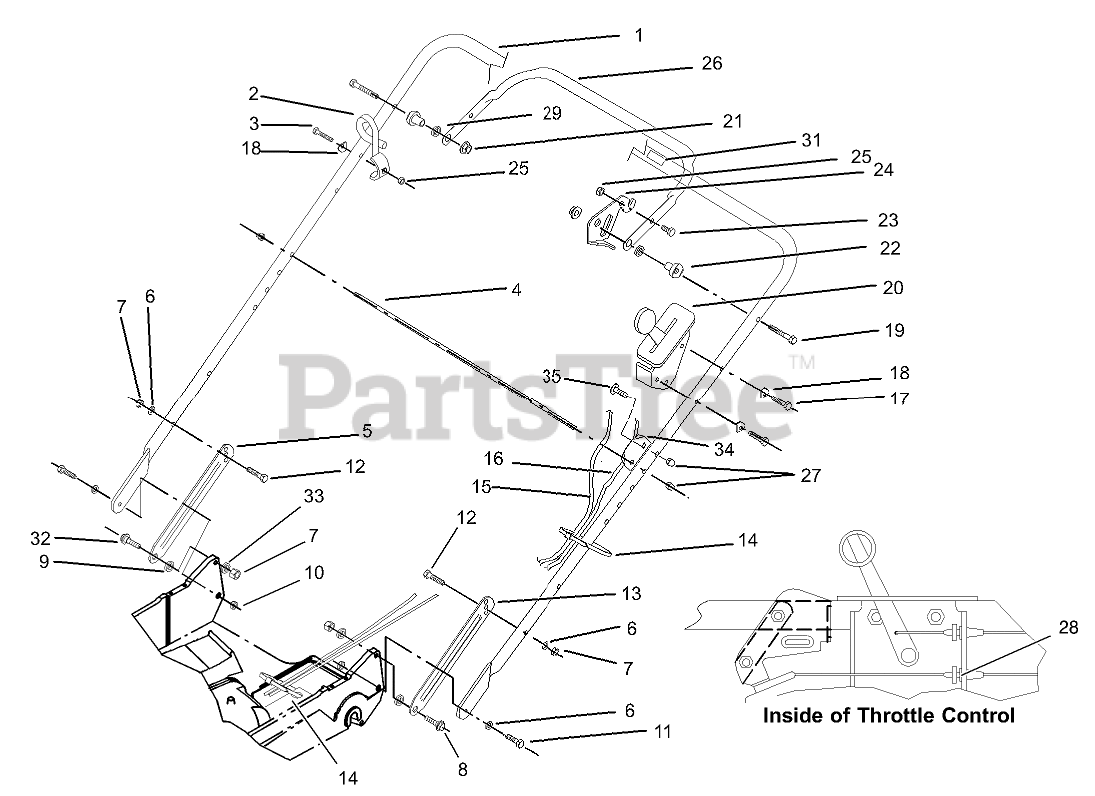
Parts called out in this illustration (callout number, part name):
2	GUIDE-ROPE
3	SCREW-HH
4	ROD-SUPPORT, BAG
5	LATCH-HANDLE, RH
6	WASHER-BELLEVILLE
7	NUT-LOCK, NI
8	SCREW-SHOULDER
9	SPACER
10	NUT-LOCK, NI
11	SCREW-HH
12	SCREW-HH
13	LATCH-HANDLE, LH
14	TIE-CABLE
15	Cable-Brake
16	CABLE-THROTTLE
17	SCREW-HH
18	WASHER
19	SCREW-HH
20	Control-Throttle
21	NUT-LOCK, NI
22	SPACER-SUPPORT
23	SCREW-HH
24	LEVER-CONTROL
25	NUT-LOCK, NI
26	BAR-CONTROL
27	NUT-CAP
28	E-RING
29	SPACER-NYLON
31	DECAL-PROTECTION, EAR
32	SCREW-SHOULDER
33	WASHER-PLAIN
34	PLATE-ALIGNING, BAG
35	SCREW-CARR
